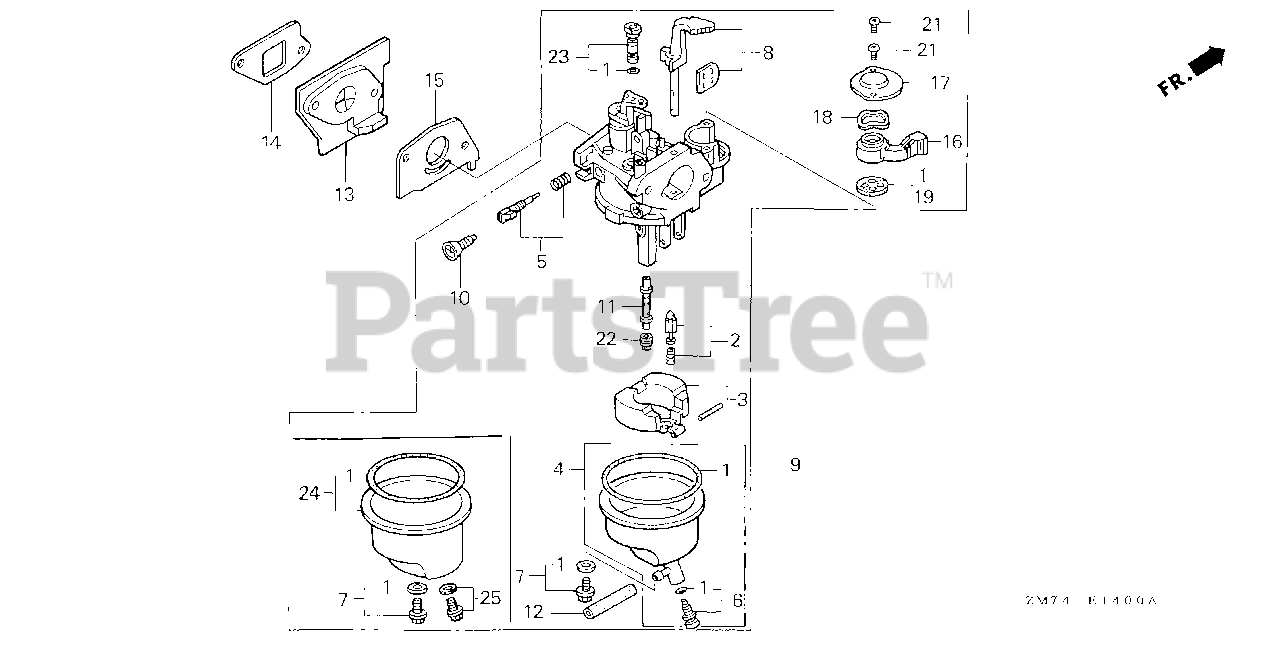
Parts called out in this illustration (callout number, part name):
1	GASKET SET
2	VALVE SET, FLOAT
3	FLOAT SET
5	SCREW SET
7	SCREW SET
8	CHOKE SET
9	CARBURETOR ASSY. (BF32E B)
10	SCREW, THROTTLE STOP
11	NOZZLE, MAIN
13	INSULATOR, CARBURETOR
14	GASKET, INSULATOR
15	GASKET, CARBURETOR
16	LEVER, VALVE
17	PLATE, LEVER SETTING
18	SPRING, VALVE LEVER
19	GASKET, VALVE
21	SCREW, PAN (3X6)
22	JET, MAIN (#50)
22	JET, MAIN (#52)
22	JET, MAIN (#55)
23	JET SET, PILOT (#35)
24	CHAMBER SET, FLOAT
25	SCREW SET, DRAIN
